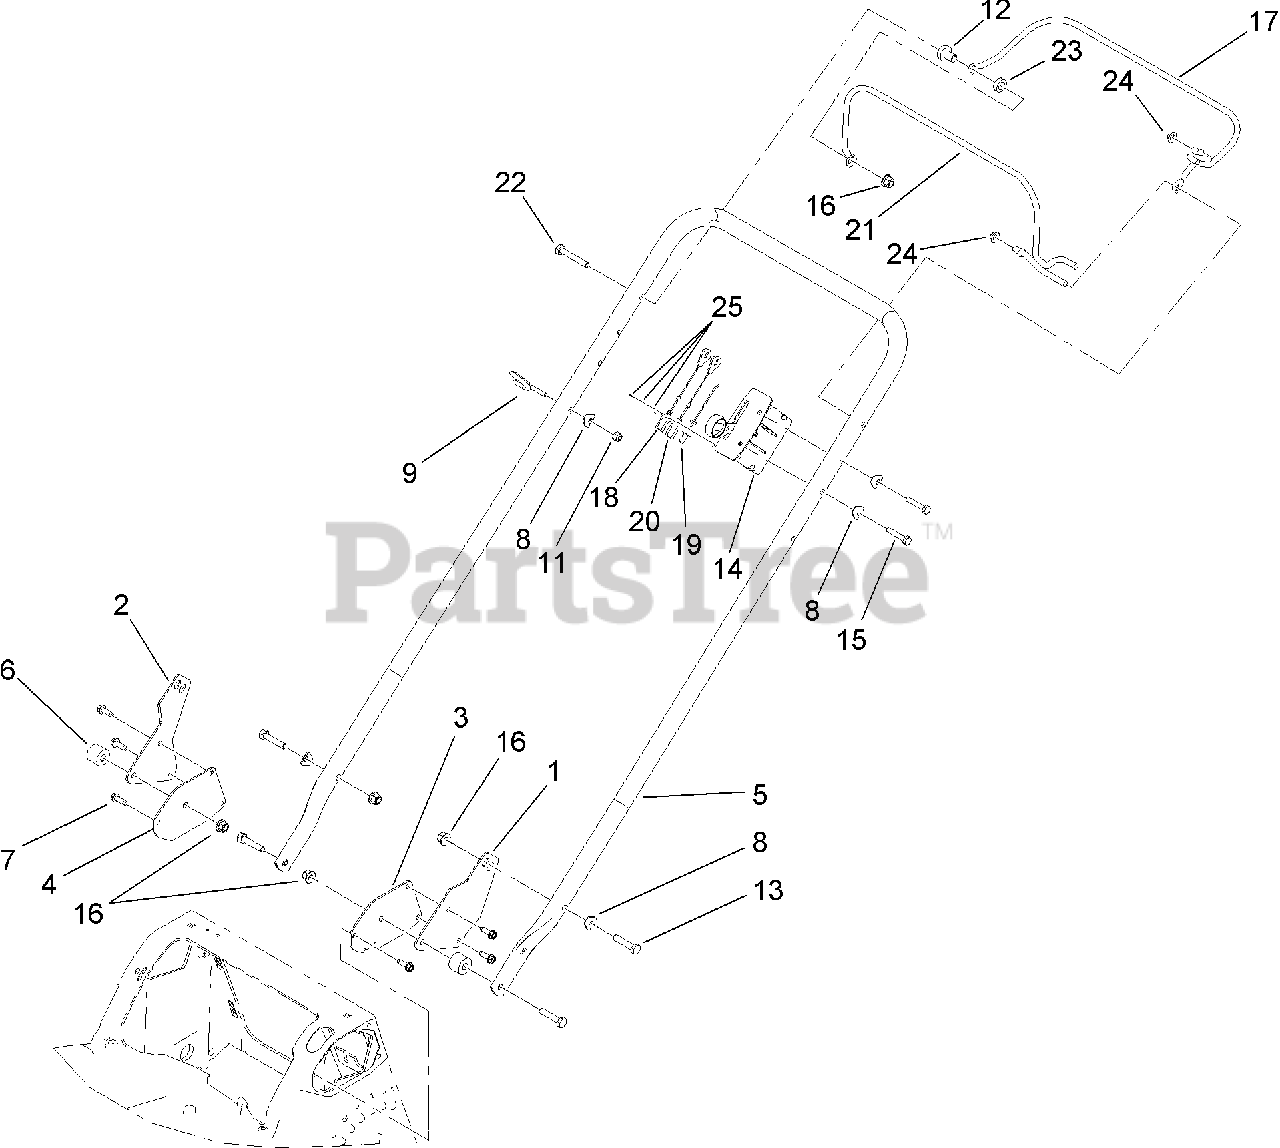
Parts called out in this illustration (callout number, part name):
1	SUPPORT-STRUT, LH
2	SUPPORT-STRUT, RH
3	PLATE-HANDLE, TRACTION
4	PLATE-HANDLE
5	HANDLE
6	SPACER-STEAMED
7	SCREW-HWHTF
9	GUIDE-ROPE
11	NUT-LOCK, NI
12	SPACER-SUPPORT
13	SCREW-HH
14	CONTROL-HEAD, THROTTLE
15	SCREW-HH
16	NUT-LOCK, NI
18	CABLE-BRAKE
19	THROTTLE CABLE ASM
20	CABLE-TRACTION
21	BAIL-TRACTION
22	SCREW-HH
23	SPACER-NYLON
24	NUT-PUSH
